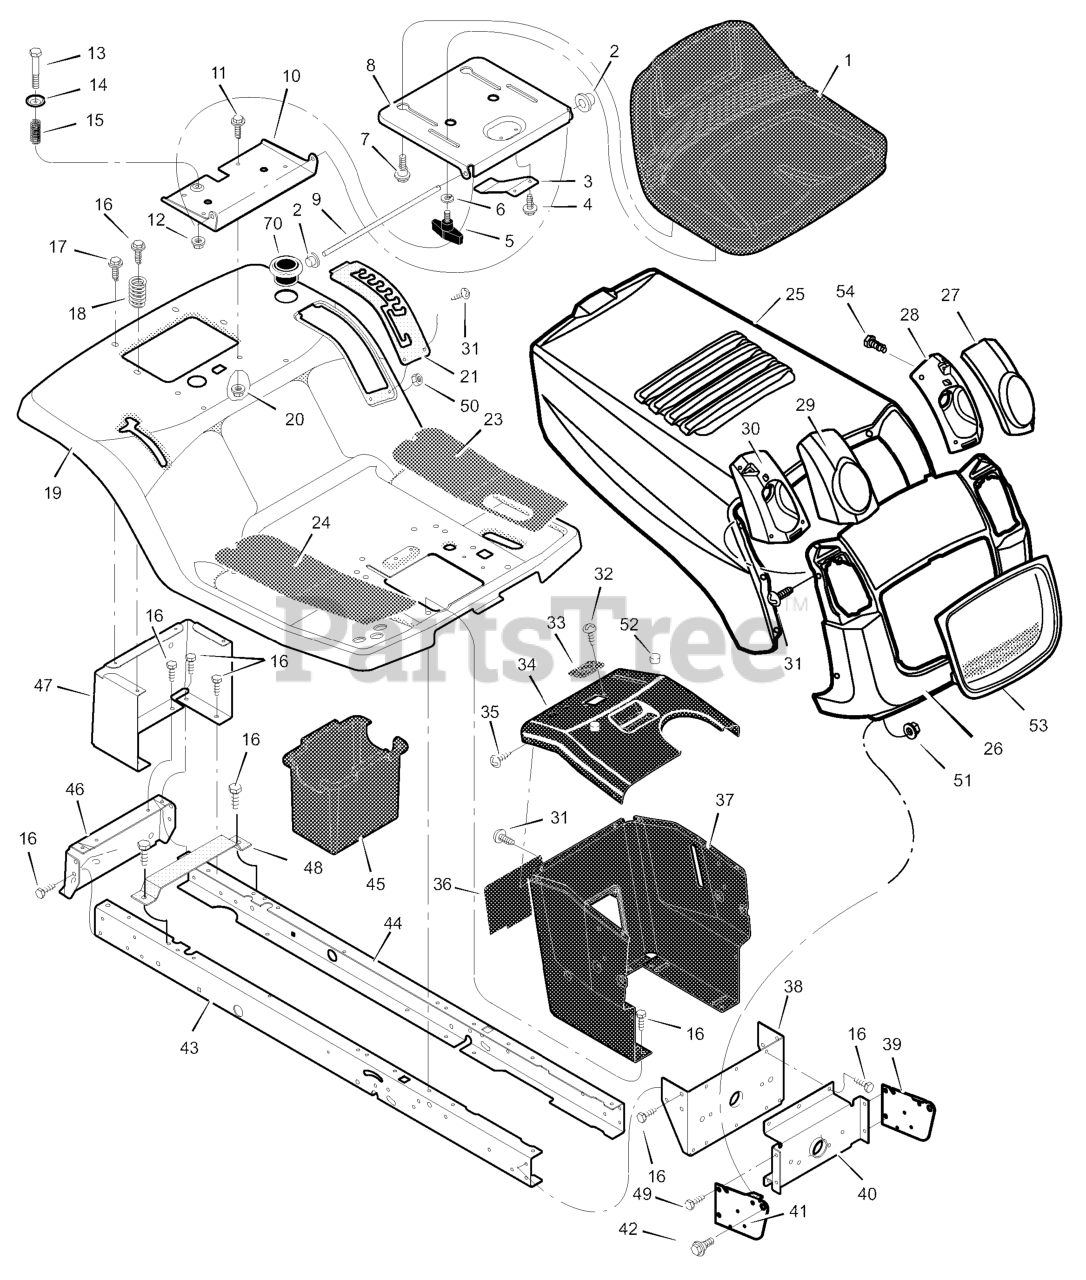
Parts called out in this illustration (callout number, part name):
1	Seat
2	Cap, Push On
5	Bolt, Wing
6	Washer
7	Bolt, Shoulder
8	Support, Seat
9	Rod, Pivot
10	Bracket, Pivot
11	Bolt
13	Bolt, Shoulder
15	Spring
19	Deck, Seat
20	Nut
21	Plate, Index
23	Mat, Left
24	Mat, Right
26	Grille
27	Lens, Left
28	Housing, Left Headlamp
29	Lens, Right
30	Housing, Right Headlamp
31	Screw
33	Bearing, Steering
36	Panel, Access
37	Support, Dash
38	Bracket, Rear Hanger
39	Support, Left Grille
40	Axle, Hanger
41	Support, Right Grille
42	Bolt, Shoulder
43	Frame, Right
44	Frame, Left
45	Container, Battery
46	Plate, Hitch
47	Panel, Rear
48	Support, Battery
52	Bumper
53	Insert, Grille
70	Holder, Cup
